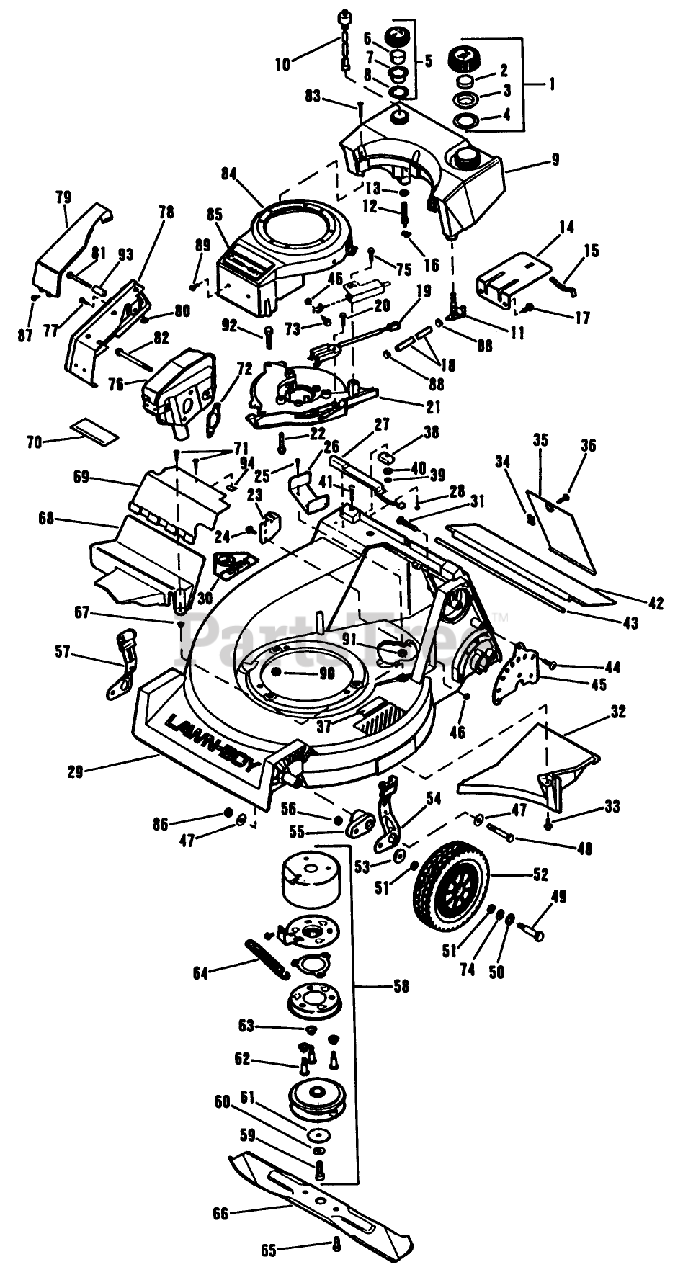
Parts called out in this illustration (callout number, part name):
1	CAP AY - FUEL M
2	BAFFLE - FOAM SM
4	GASKET-FUELCAP SM
5	CAP AY. OIL M
6	FILTER S
10	SWITCH AY-OIL S
11	DISC/LB SER.BUL.#6
14	DISC. LB SER.BUL.#6
15	SPRING
18	GAS LINE SM
19	SWITCH INT.LOCK S
22	SCREW-SEMS F
26	BELT GUIDELB
32	CHUTE BAFFLE NYL
34	SPEED NUT LARSON
35	DOOR-ACCESS ELECT.
36	SCREW-CROSS RECESS
44	SCREW-BHTF
45	PLATE HGT CMS
46	LOCKNUT E
47	Washer
49	BOLT WHEEL QUAL
50	SPACER
51	WASHER
52	WHEEL&TIRE 8" TRI
53	Washer
54	KNOB & SPRING CMS
55	ARM HGT ADJ *BLACK
57	KNOB & SPRING CMS
61	WASHER
62	SCREW,SHOULDER SM
64	SPRING
65	SCREW SEMS
66	21" Blade
67	NUT-CLIP
71	SCREW S
72	GASKET - EXH SM
74	WASHER
75	SCREW-HH
77	SCREW S
78	MUFFLER GUARD AY
79	COVER MUFFLER CP
80	NUT-PUSH
81	SCREW SM
82	SCREW-SEMS
83	DISC.LB SER.BUL.#6
85	APPLIQUE SM
86	LOCKNUT
87	SCREW SM
88	HOSE CLAMP SM
90	NUT-LOCK F
91	NUT C/LOCK E
92	SCREW
93	SPACER S
94	NUT-SPEED
